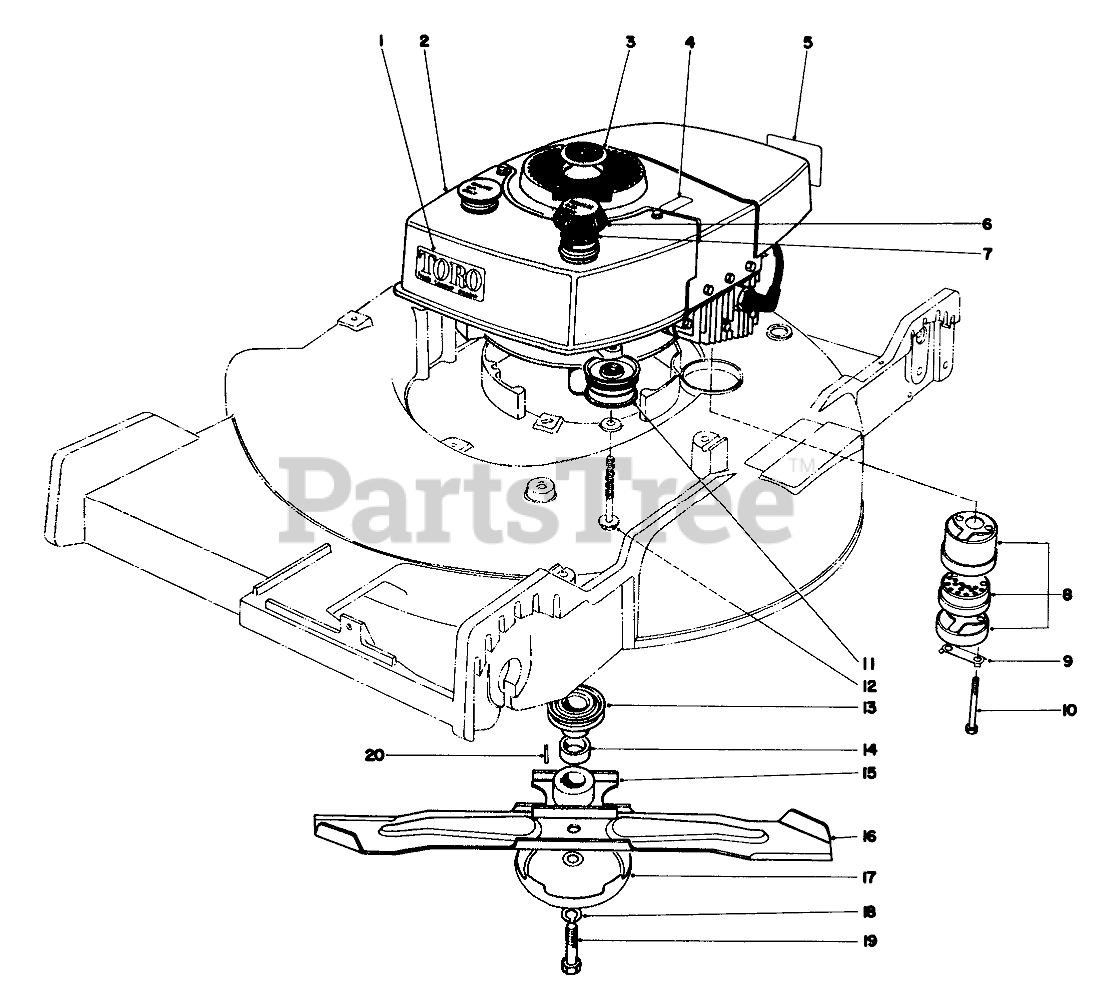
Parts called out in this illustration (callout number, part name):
1	High Torque
2	Engine
3	Plug Button
4	Decal-Caution
5	Decal Maintenance
6	Gas Cap (Incl. Ref. #7)
7	Gasket
8	MUFFLER ASM
9	CLIP - LOCKING
10	SCREW-HH
11	Idler Pulley
12	3/8-16 X 2-3/4 CAPSCR
13	Pulley
14	Spacer Pulley
15	BLADE RETAINER WA(BLACK)
16	Blade
17	AntiScalp Cup
18	WASHER-LOCK
19	BLADE SCREW
20	Key Square
